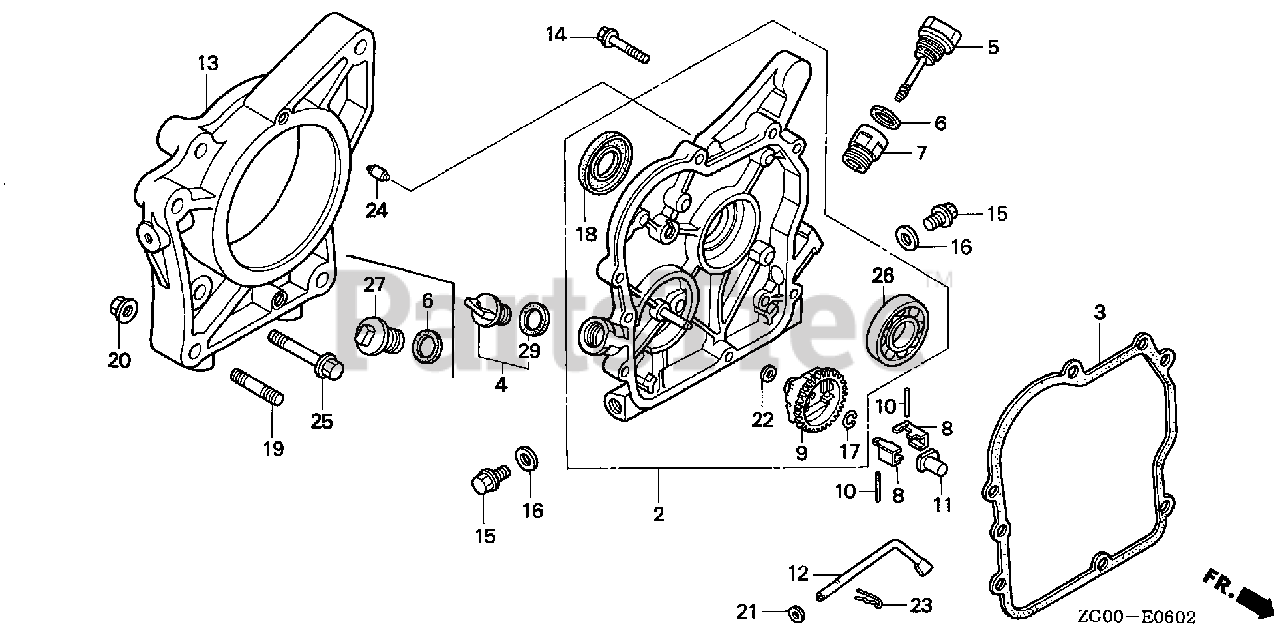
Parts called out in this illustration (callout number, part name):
2	COVER ASSY., CRANKCASE
3	GASKET, CASE COVER
5	CAP, OIL FILLER
6	GASKET, OIL FILLER CAP
8	WEIGHT, GOVERNOR
9	HOLDER, GOVERNOR WEIGHT
10	PIN, GOVERNOR WEIGHT
11	SLIDER, GOVERNOR
12	SHAFT, GOVERNOR ARM
13	HOUSING, RR. CLUTCH
14	BOLT, FLANGE (6X28)
15	BOLT, DRAIN PLUG
16	WASHER, DRAIN PLUG (10.2MM)
17	CLIP, GOVERNOR HOLDER
18	OIL SEAL (17X30X6) (NOK)
19	BOLT 2, STUD (8X32)
20	NUT, FLANGE (8MM)
21	WASHER, PLAIN (5MM)
22	WASHER, PLAIN (6MM)
23	PIN, LOCK (8MM)
24	PIN, DOWEL (6X10)
25	BOLT, FLANGE (8X38)
26	BEARING, RADIAL BALL (6203)
